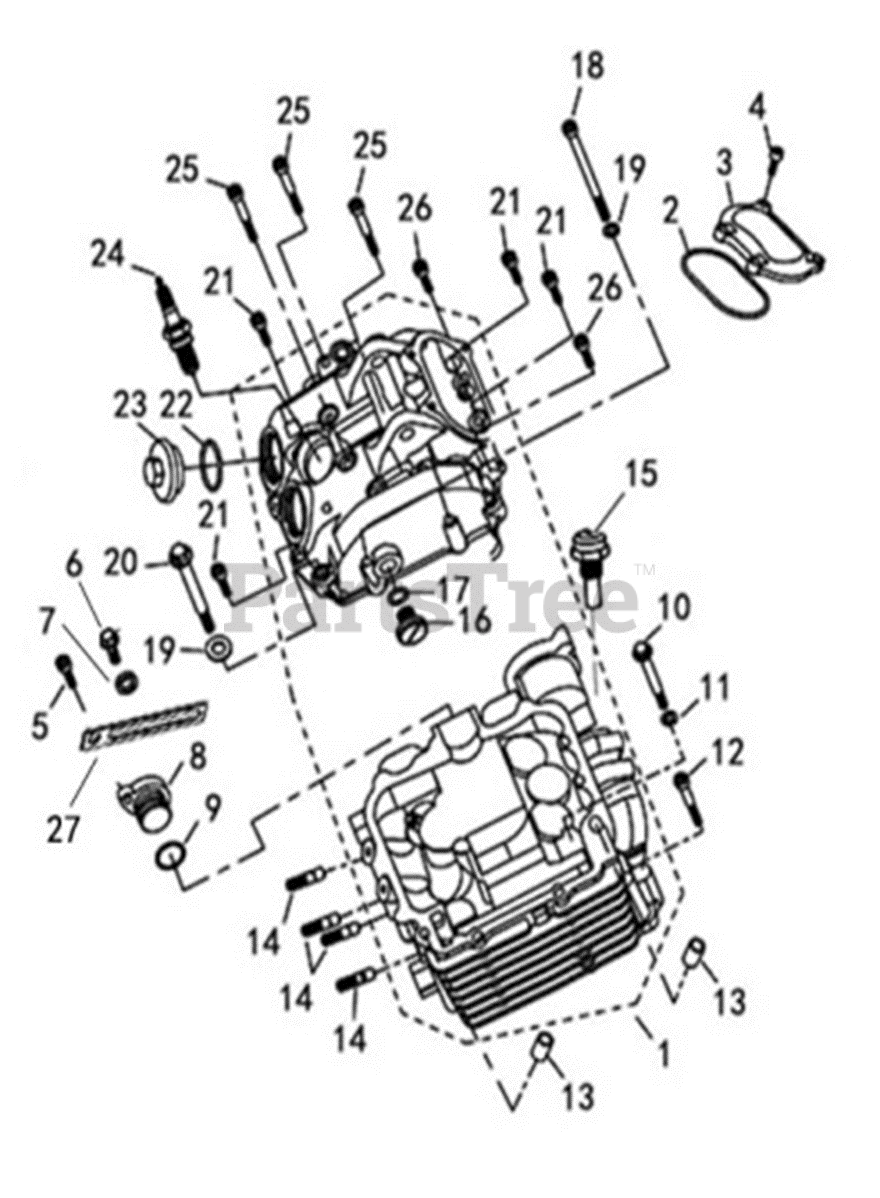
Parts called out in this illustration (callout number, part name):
1	CYLINDER HEAD (BARE)
2	O-RING 71.5X3
3	INTAKE VALVE COVER
4	HEX HEAD CAP SCREWM6X20
5	HEX HEAD CAP SCREWM6X20
6	HEX FLANGE BOLT M6X12
7	ALUMINUM WASHER 6X12X1.5
8	CAMSHAFT END COVER
9	O-RING 18 x 2.4
10	CYLINDER BOLTS M9X109
11	WASHER 10X19X2
12	HEX HEAD CAP SCREW M6X50
13	DOWEL PIN 10X16
14	STUD M8X45
15	3 WIRE TEMP SENSOR
16	SMALL PEEP HOLE COVER
17	O-RING 13.4X2.35
18	HEX HEAD CAP SCREW M6X130
19	ALUMINUM WASHER 6X12X2
20	HEX HEAD CAP SCREWM6X115
21	HEX HEAD CAP SCREW M6X25
22	O-RING 32.7X3.1
23	EXHAUST VALVE COVER
24	SPARK PLUG NGK UV
25	HEX HEAD CAP SCREW M6X55
26	HEX HEAD CAP SCREW M6X40
